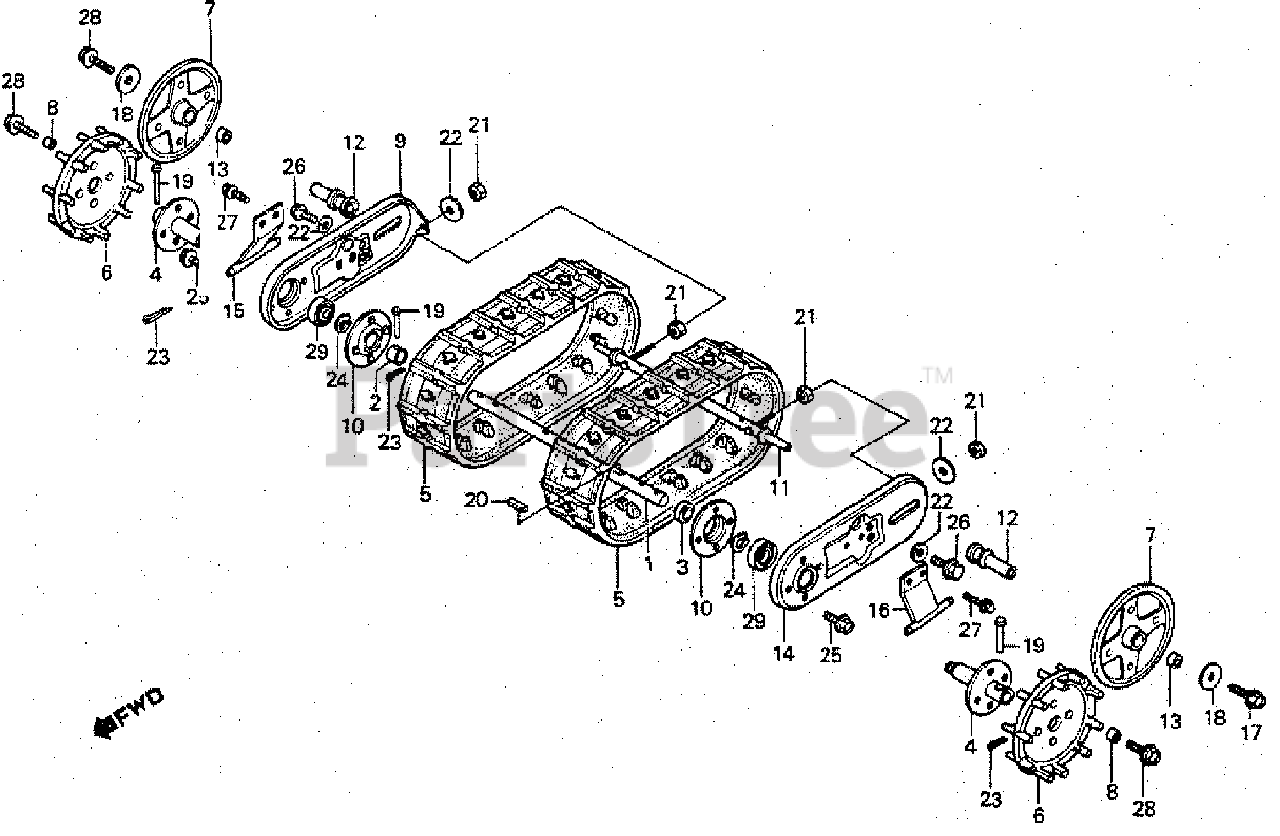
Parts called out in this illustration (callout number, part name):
1	SHAFT, WHEEL
2	COLLAR, WHEEL SHAFT
3	COLLAR, WHEEL SHAFT (B)
4	HUB, CRAWLER
5	CRAWLER (NOT AVAILABLE)
6	SPROCKET, CRAWLER
7	ROLLER, CRAWLER (NOT AVAILABLE)
8	COLLAR, SPROCKET (NOT AVAILABLE)
9	PLATE, R. CRAWLER
10	HOLDER, CRAWLER BEARING
11	PIPE, CRAWLER (NOT AVAILABLE)
12	SHAFT, ROLLER (NOT AVAILABLE)
13	BUSH, ROLLER
14	PLATE, L. CRAWLER
15	GUIDE, R. CRAWLER
16	GUIDE, L. CRAWLER
17	BOLT, L. (8X22)
18	WASHER, LOCK (8MM)
19	PIN (6.2X38)
20	KEY (5X5X21)
21	NUT, HEX. (8MM)
22	WASHER, PLAIN (8MM)
23	PIN, COTTER (3.0X18)
24	CIRCLIP (OUTER) (25MM)
25	BOLT, FLANGE (6X10)
26	BOLT, FLANGE (8X12)
26	BOLT, FLANGE (8X14)
27	BOLT, FLANGE (8X16)
27	BOLT, FLANGE (8X14)
28	BOLT, FLANGE (8X20)
29	BEARING, RADIAL BALL (6005UU)
